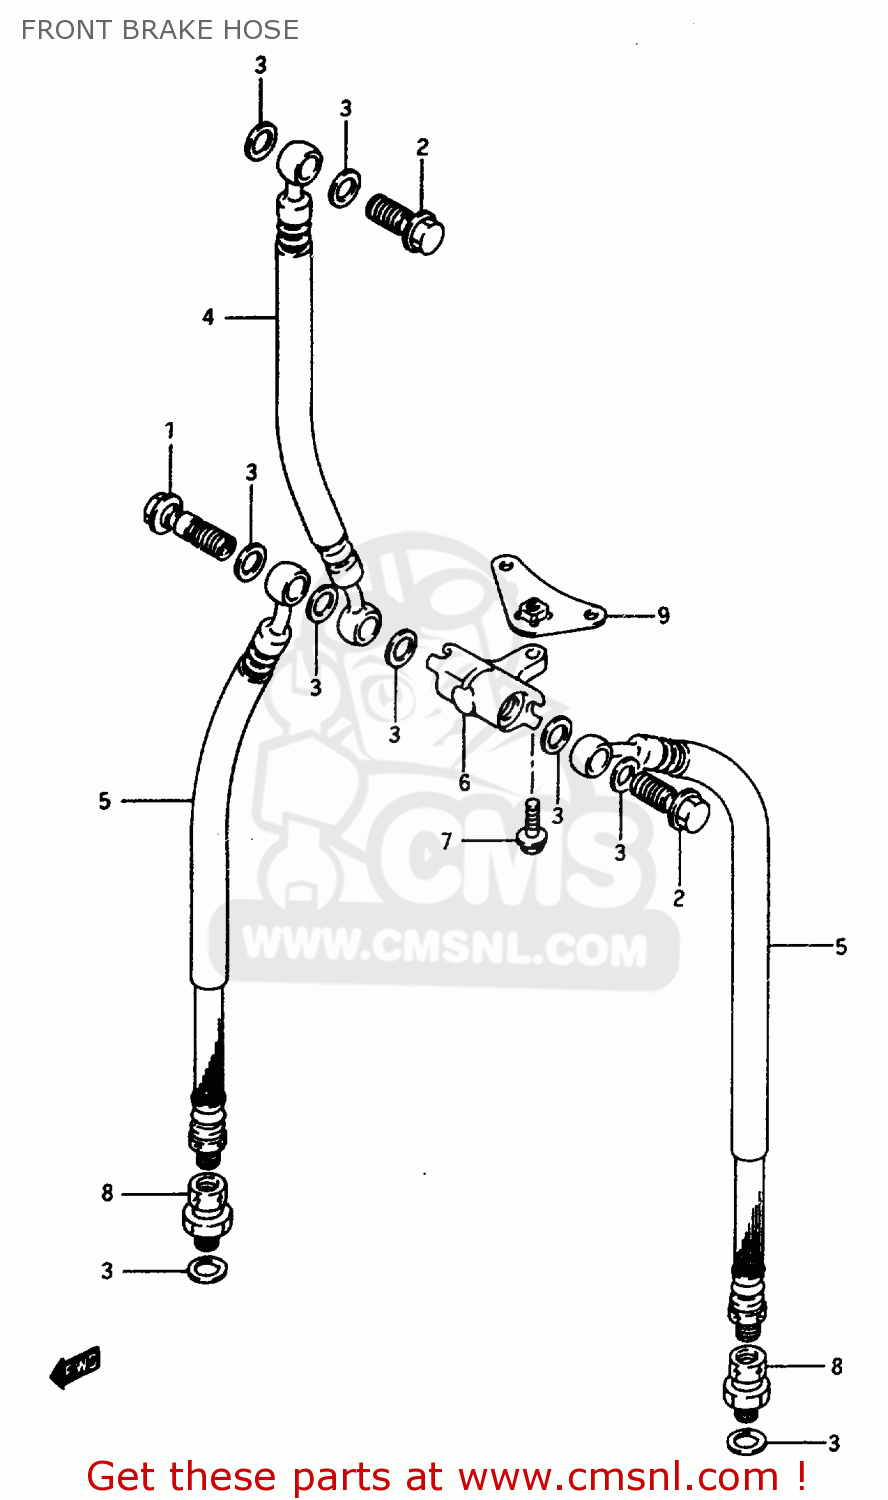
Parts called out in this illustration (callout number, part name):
1	BOLT UNION
2	BOLT UNION
3	WASHER(10X15X1.5)
4	HOSE,FR BRAKE NO.1
5	HOSE,FR BRAKE NO.2
6	JOINT,BRAKE HOSE
7	BOLT
8	ADAPTER,BRAKE HOSE
9	PLATE,FRONT BRAKE JOINT
